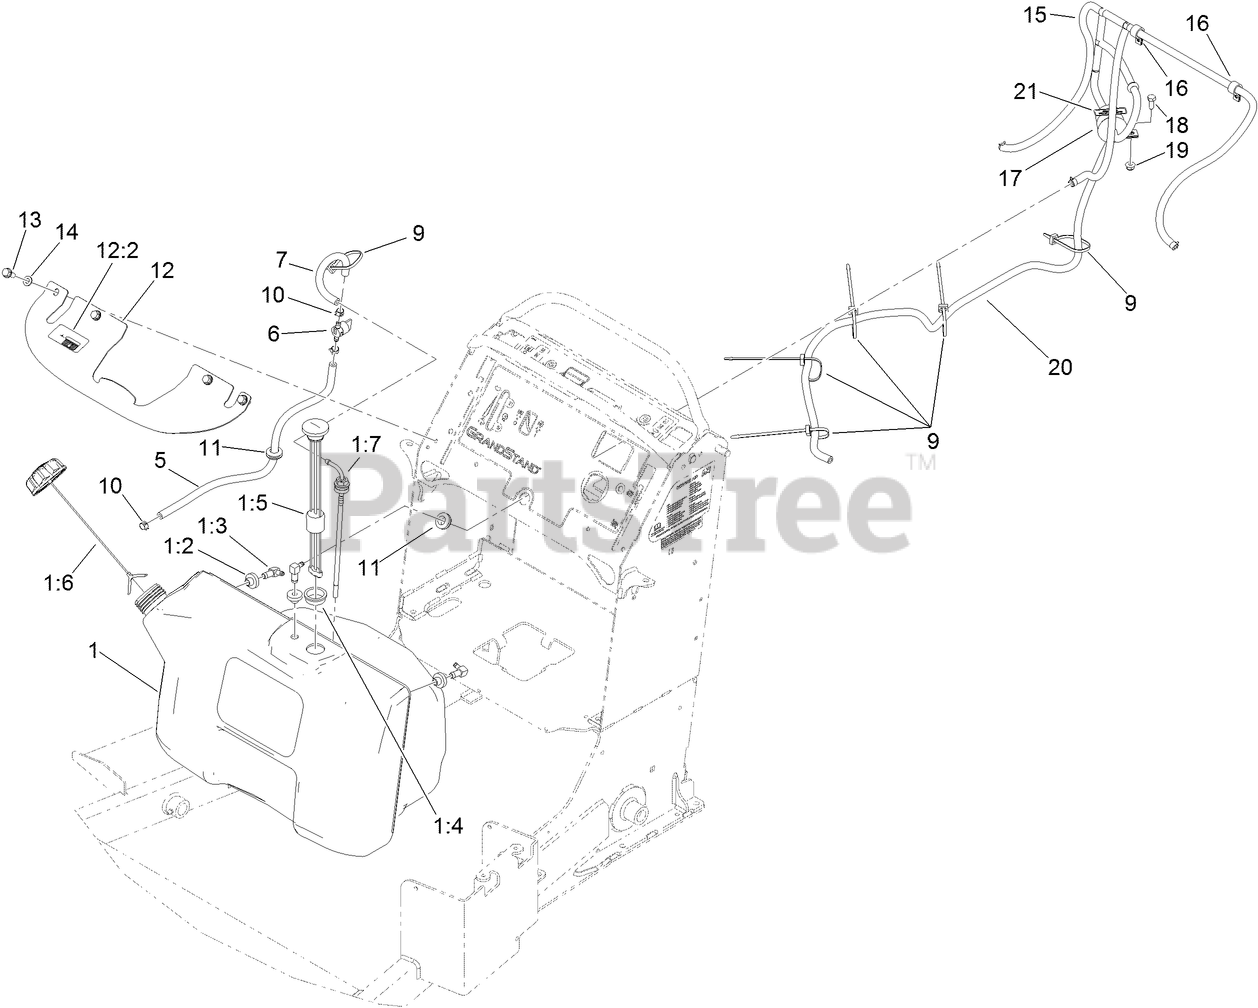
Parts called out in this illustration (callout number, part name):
1	TANK ASM
1:2	BUSHING
1:3	ELBOW-90 DEG
1:4	GROMMET
1:5	GUAGE-FUEL
1:6	CAP-FUEL, RATCHETING
1:7	FITTING-FUEL, BULKHEAD
5	HOSE-FUEL
6	VALVE-FUEL
7	HOSE-FUEL
9	TIE-CABLE
10	CLAMP-HOSE
11	GROMMET
12	BRACKET-TANK
12:2	DECAL-FILL, FUEL
13	SCREW-HWHTF
14	WASHER-FLAT
15	VENT HOSE ASM
16	CLAMP-CABLE
17	CLAMP-R
18	SCREW-HH
19	NUT-HF, NI
20	HOSE-FUEL
21	DECAL-FILTER, EMISSIONS
